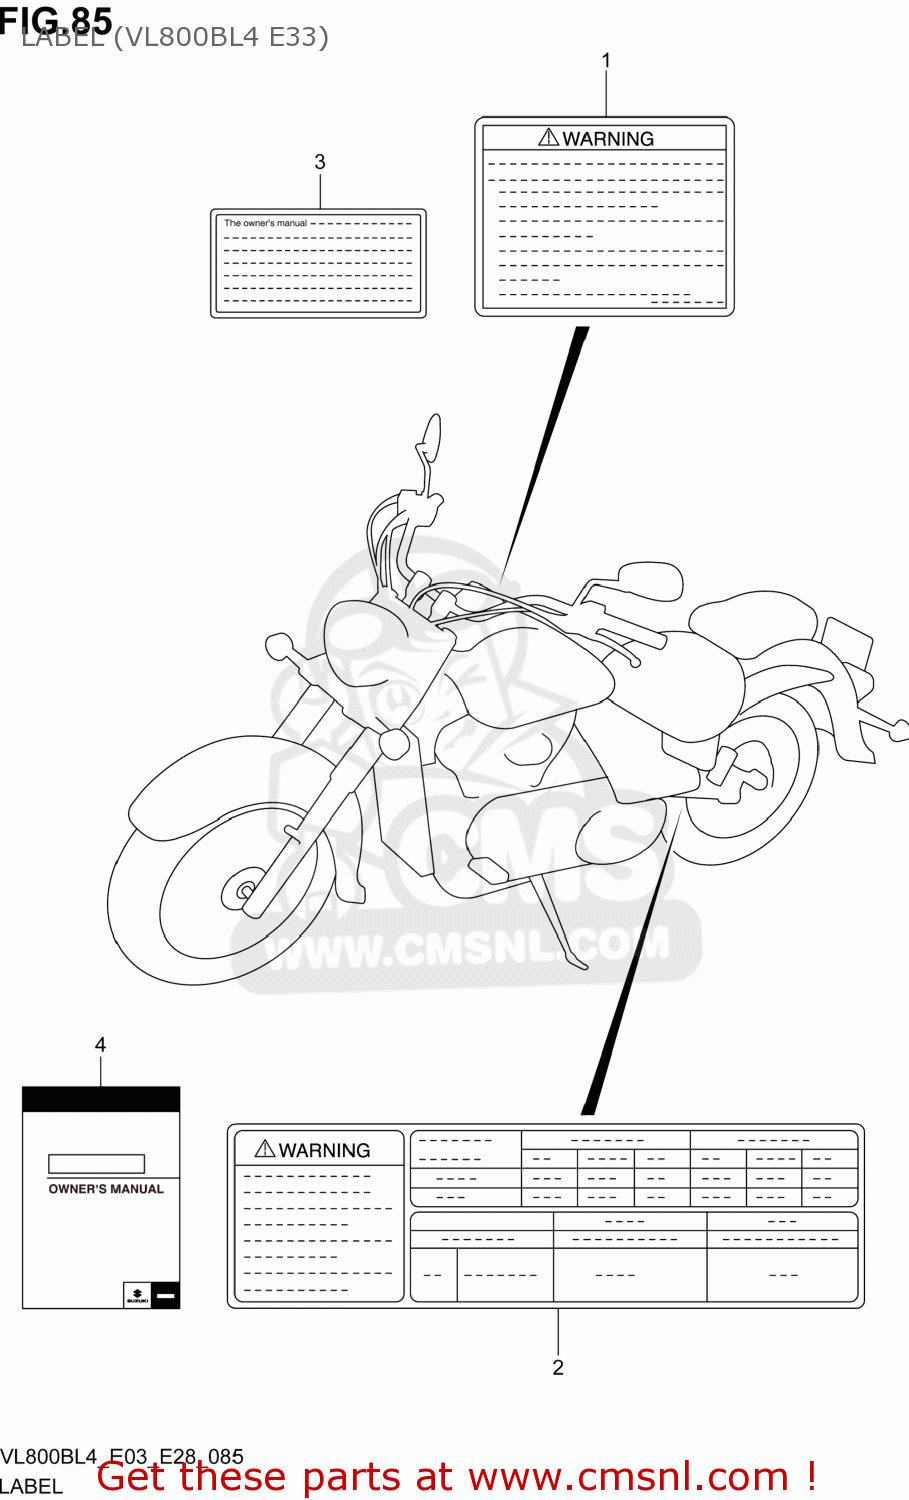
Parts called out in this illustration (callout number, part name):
1	LABEL,GENERAL WARNING
2	LABEL,TIRE INFORMATION
3	LABEL,MANUAL NOTICE
4	MANUAL,OWNER'S
